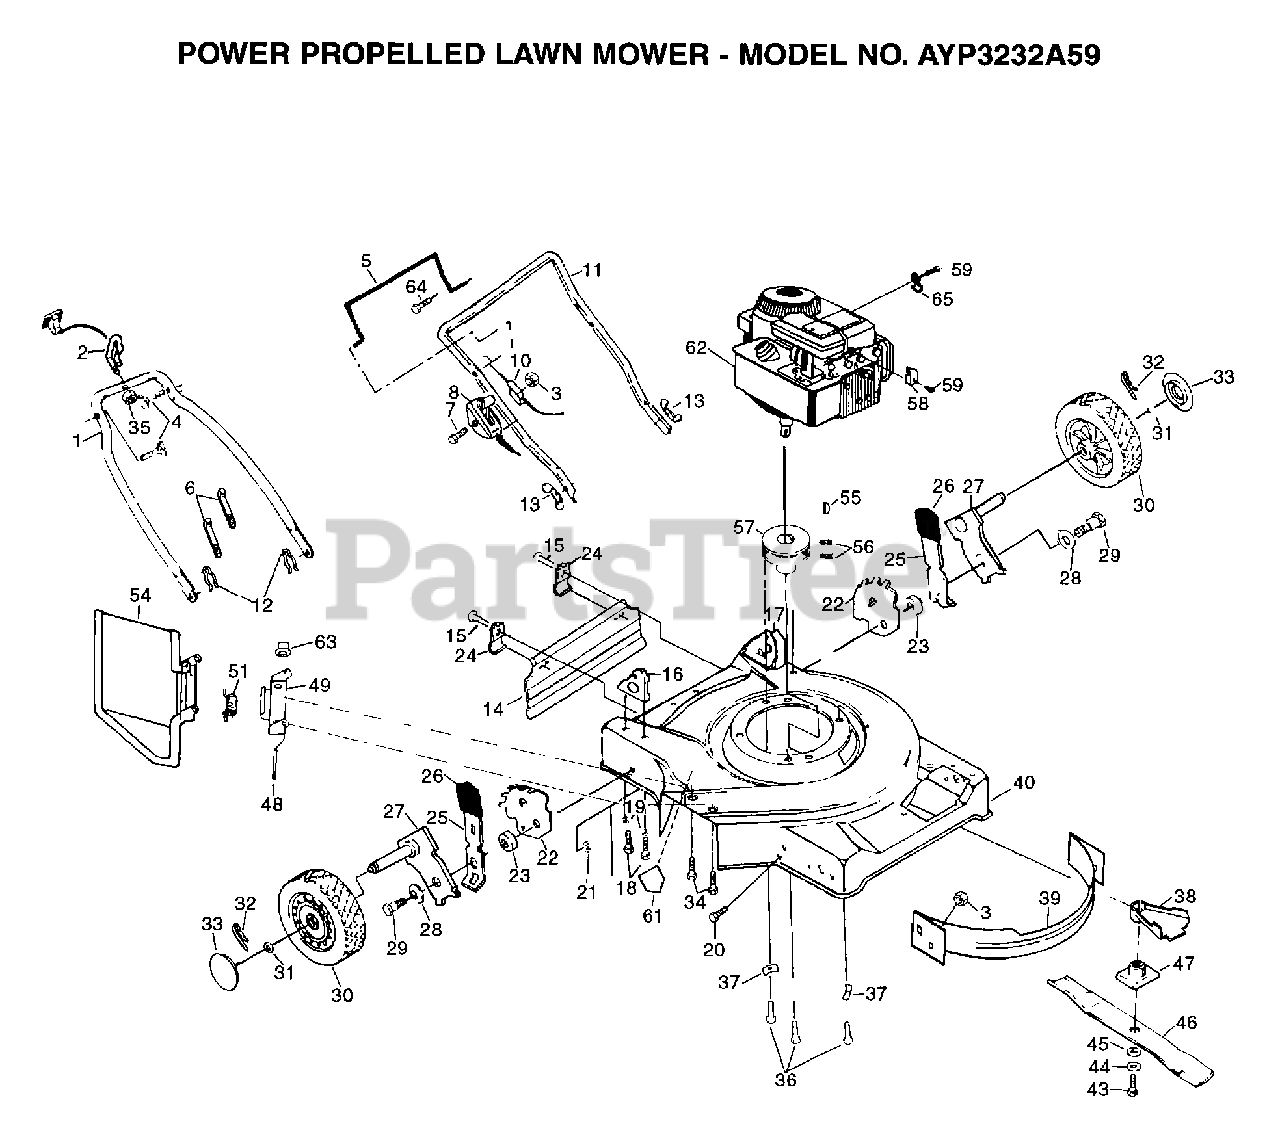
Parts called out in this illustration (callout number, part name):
2	ROPER GUIDE PM
4	BOLT.HANDLE.LM
5	CONTROL BAR
7	SCREW.HXHD.WASH.
8	CONTROL THROTTLE
10	"CABLE,ENG ZONE CO"
12	HAIRPIN COTTER
13	"NUT,WING PM"
14	SKIRT.REAR.22SD.
15	TAPPING SCREW
18	SCREW
19	STEEL WASHER
20	SCREW
21	LOCKNUT PM
22	BRACKET.ADJ.9POS.
24	"BRKT,DEFL PM"
25	SPRING SELECTOR
26	KNOB PM
27	AXLE ARM
28	"WASHER, BELLEVIL."
29	BOLT SHLD 3/8-16
31	WASHER
32	RETAINER CLIP PM
33	HUB CAP
34	SCREW
36	SCREW
39	BAFFLE FRONT 22SD
40	KIT.HSG.22SD.FWGD
43	SCREW
44	LOCKWASHER
45	"WASHER,HARDEN"
46	"BLADE.MULCH.22"""
47	ADAPTOR.BLADE.LM
48	"ROD,HINGE "
49	"BRKT,HSG"
51	"SPRING,TORSION"
55	HI PRO KEY PM
56	SCREW
57	ENGINE.PULLEY.FWG
58	CABLE CLAMP
59	SCREW PM
61	DECAL-DANGER PM
63	PUSH ON SPEED NUT
64	"SCREW,PAN HD"
65	GUIDE CLIP PM
